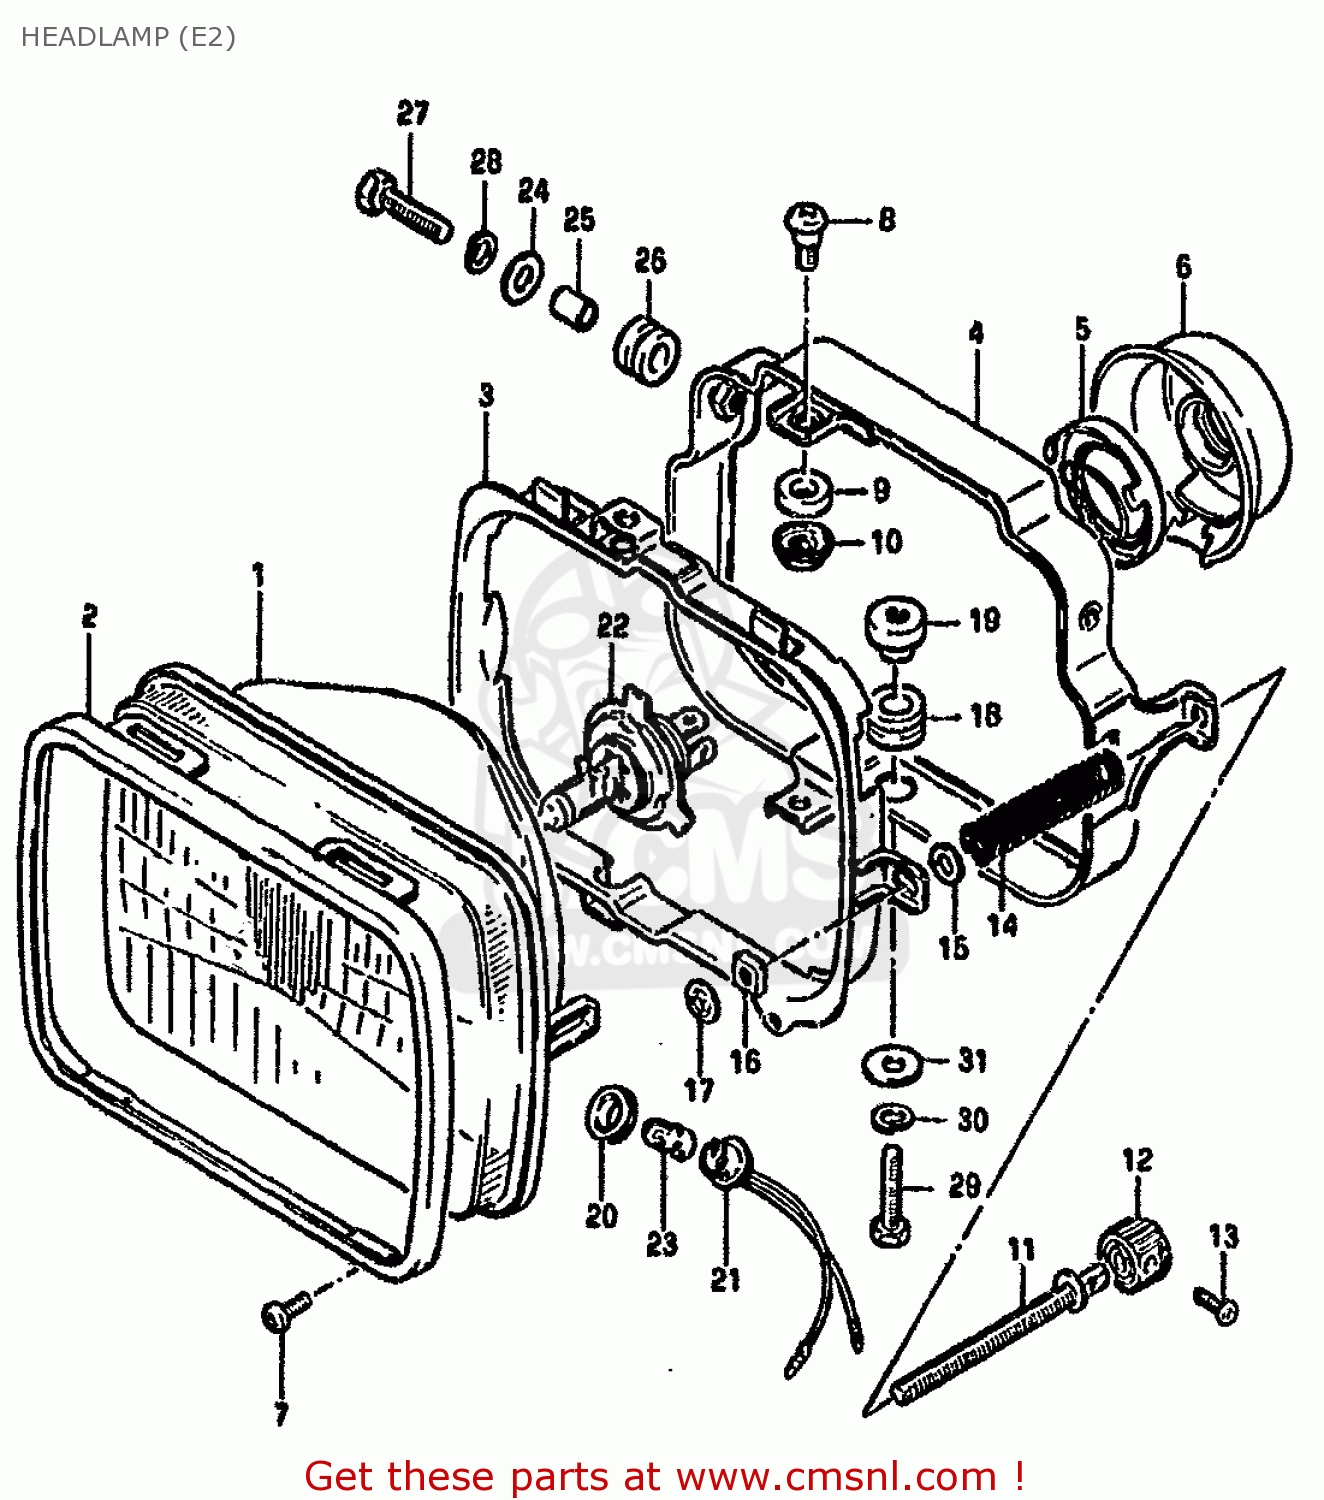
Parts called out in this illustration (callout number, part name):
1	UNIT
2	RETAINER
3	RING,MOUNTING
4	HOUSING
5	HOLDER, BULB
6	COVER,HEADLAMP SOCKET
7	SCREW
8	SCREW
9	SPACER
10	NUT,ADJUSTING
11	SCREW,ADJUSTING
12	KNOB,ADJUSTER
13	SCREW
14	SPRING
15	WASHER
16	NUT
17	NUT,HEADLAMP ADJUSTER
18	CUSHION
19	NUT
20	JOINT,RUBBER
21	SOCKET
22	BULB(12V60/55W,H4)
23	BULB(12V4W)
24	WASHER
25	SPACER (6.1X8X9.5)
26	CUSHION
27	BOLT
28	LOCK WASHER
29	SCREW(6X20)
30	LOCK WASHER
31	WASHER
